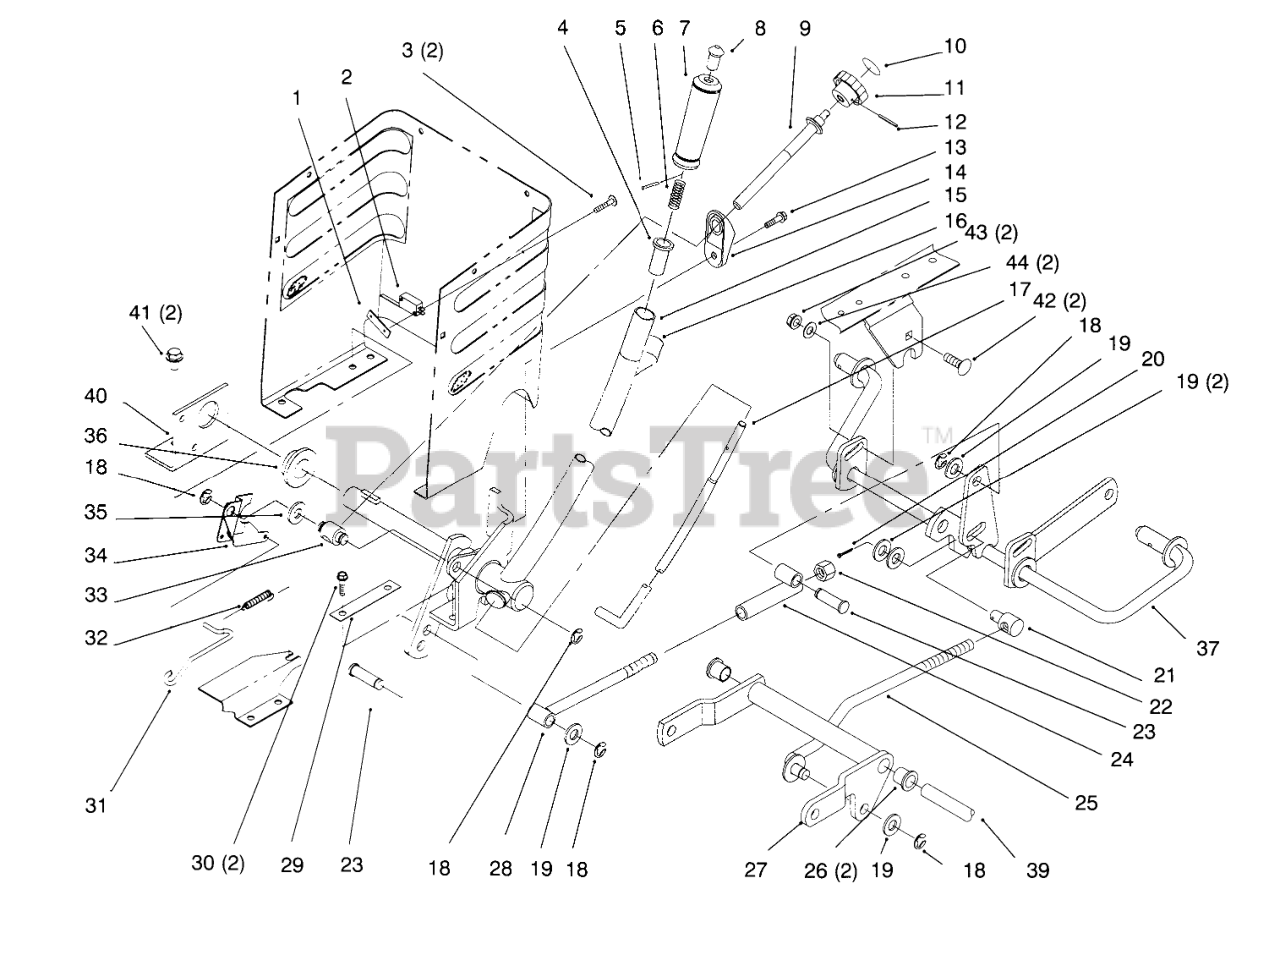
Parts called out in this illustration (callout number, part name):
1	NUT-SPEED
2	SWITCH-MICRO
3	SCREW-HH
4	RETAINER-SPRING
5	PIN-SPIROL
6	SPRING-COMPRESSION
7	GRIP-HANDLE
8	TIP-ROD
9	ROD - HOC
10	DECAL-HEIGHT KNOB
12	PIN-SPIROL
13	SCREW-HWH
14	WEDGE - HOC
15	Lever-Lift
16	DECAL-LIFT
17	ROD-LEVER, LIFT
18	RING-RETAINING, EXTERNAL
19	WASHER-FLAT
20	PIN-COTTER
21	ROD-TRUNNION LIFT
22	NUT-LOCK, NI
26	BUSHING-FLANGE
27	ARM-PIVOT
30	SCREW-HWHTF
31	ROD - HOC INDICATOR
32	SPRING - EXTENSION
33	TRUNNION
34	PLATE - HOC GAGE
35	WASHER
36	BEARING-FLANGE
37	SHAFT-GAGE
39	SHAFT
40	Bracket-Pivot Linkage
41	SCREW-HWHTF
42	BOLT-CARR
43	WASHER-FLAT
44	NUT-LOCK, NI
